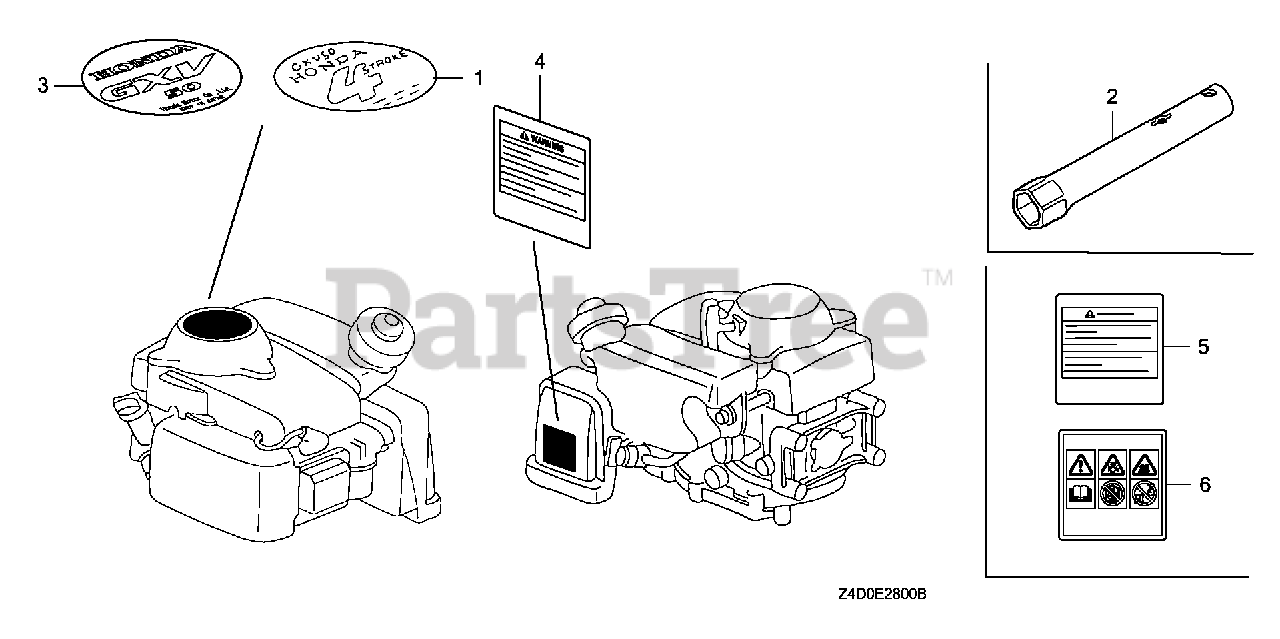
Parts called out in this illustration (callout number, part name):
1	EMBLEM (GXV50)
2	WRENCH, SPARK PLUG
3	EMBLEM (GXV50)
4	MARK, OPERATOR CAUTION (ENGLISH)
5	MARK, OPERATOR CAUTION (FRENCH)
6	MARK, OPERATOR CAUTION (PICTOGRAPH)
